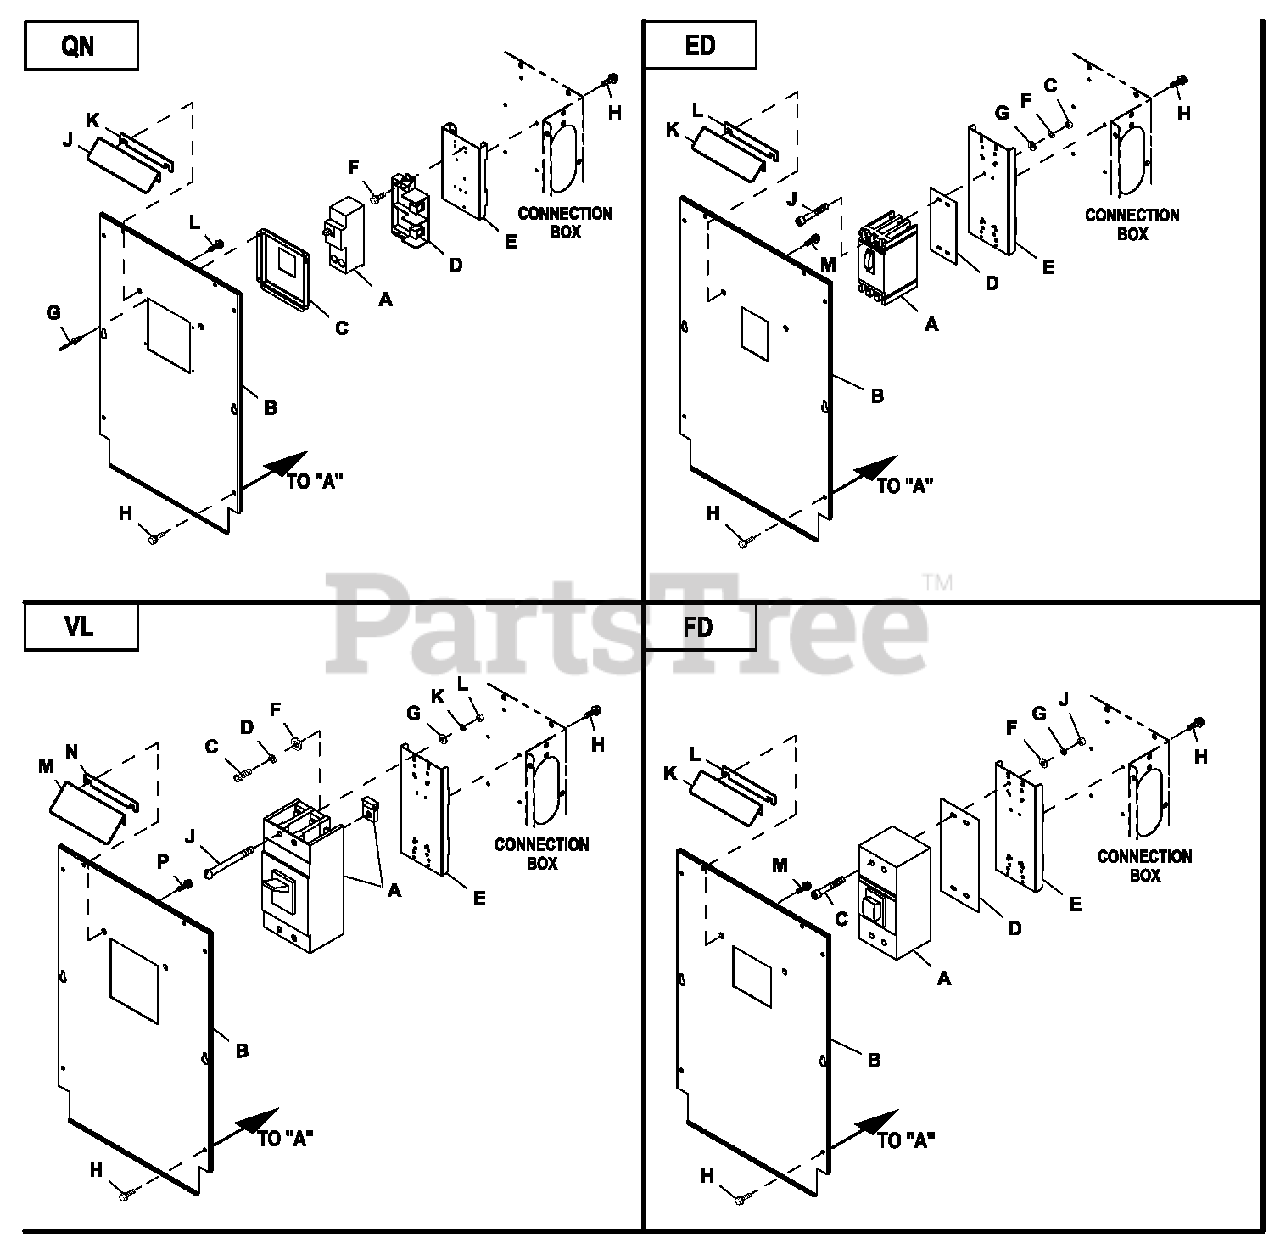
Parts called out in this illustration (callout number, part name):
A	ROTOR-2390-35KD1 CPL
B	ROTOR-2390-45KD1 CPL (G2)
C	ROTOR-2390-35KD1 CPL (G2)
D	ROTOR 25KW 3PH DIRECT 390 1800
E	ROTOR 25KW 1PH DIRECT 390 1800
F	SCREW HHTT M5-0.8 X 10 BP
G	RIVET POP .125 X .275 SS
H	SCREW HWHT M6-1 X 16 N WA Z/JS
J	STATOR-390 45K 2P 1PH DIRECT
K	STATOR-2390-35AD1 CPL
L	STATOR-2390-35KD1 CPL
A	STATOR-2309-45KW 2P 3PH 208V
B	STATOR-2309-45-KD1 CPL
C	N UT HEX #10-32 STEEL
D	I N SULATOR CB S(ED-3P)
E	STA N DOFF CB MOU NT CO N BOX
F	WASHER LOCK #10
G	WASHER FLAT#10ZIN C
J	SCREW RHM #10-32 X 4-1 /2
K	SHIELD-SM CIRCUIT BREAKER
L	GASKET-CB SHIELD C2
M	SCREW HWHTF M6-1.0X16
A	CB 0300A 3P 600V S JG-VL LL
B	COVER CB S JG VL C2 CONBOX
C	SCREW SHC M8-1.25 X 20 C12.9
D	WASHER LOCK M8-5/16
E	STANDOFF CB MOUNT CONBOX
F	WASHER FLAT 5/16-M8 ZINC
G	WASHER FLAT#10ZINC
J	SCREW RHM 10-32X4
K	WASHER LOCK #10
L	NUT HEX #10-32 STEEL
M	SHIELD-LGE CIRCUIT BREAKER
N	GASKET-CB SHIELD C2
P	SCREW HWHTF M6-1.0X16
A	CB 0150A3P 600V S FD6 LL
B	COVER CB S FD6 C2 CONBOX
C	SCREW SHC 1/4-20X4.5 G8.8 NZ
D	INSULATOR CB FD FRAME 30MIL
F	WASHER FLAT 1/4-M6 ZINC
G	WASHER LOCK M6-1/4
J	NUT HEX 1/4-20 STEEL
